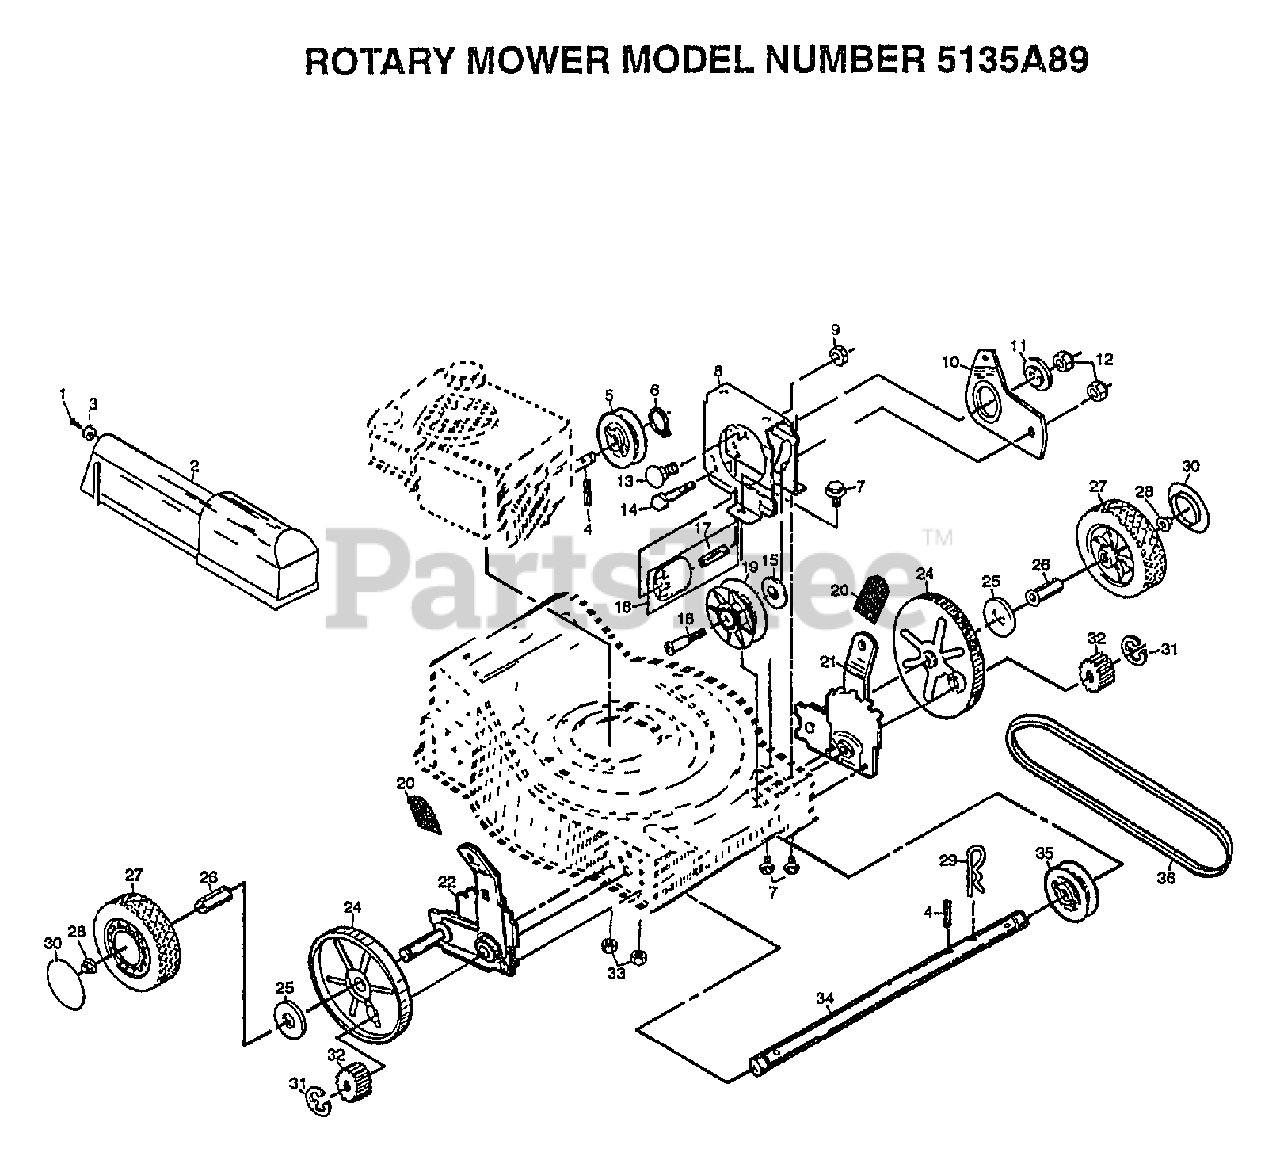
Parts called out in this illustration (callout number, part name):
1	SCREW HXHD 10-24
2	DRIVE COVER
3	FASTNER PUSH DRCV
4	DRIVE PAWL
6	RETAINING RING ST
7	SCREW
8	"CLUTCH,FRAME"
9	LOCKNUT
11	SPACER PM
12	LOCKNUT
13	CARRIAGE BOLT
14	BOLT 1/4-20-1 1/2
15	SPACER PM
17	IDLER SPACER
18	SHOULDER BOLT
19	IDLER PULLEY
20	KNOB PM
21	WHEEL ADJ ASSY LH
22	WHEEL ADJ ASSY RH
24	DUST SHROUD PM
25	WASHER FLUT
26	BUSHING.HEX
27	WHEEL DRIVE 8X2
28	NUT.HXFLG.LOCK.
29	RETAINER CLIP PM
30	HUB CAP
31	E-RING.7/16.RE.
32	PINION.GEAR
34	SHAFT.DRIVE.17.81
35	DRIVE PULLEY PM
